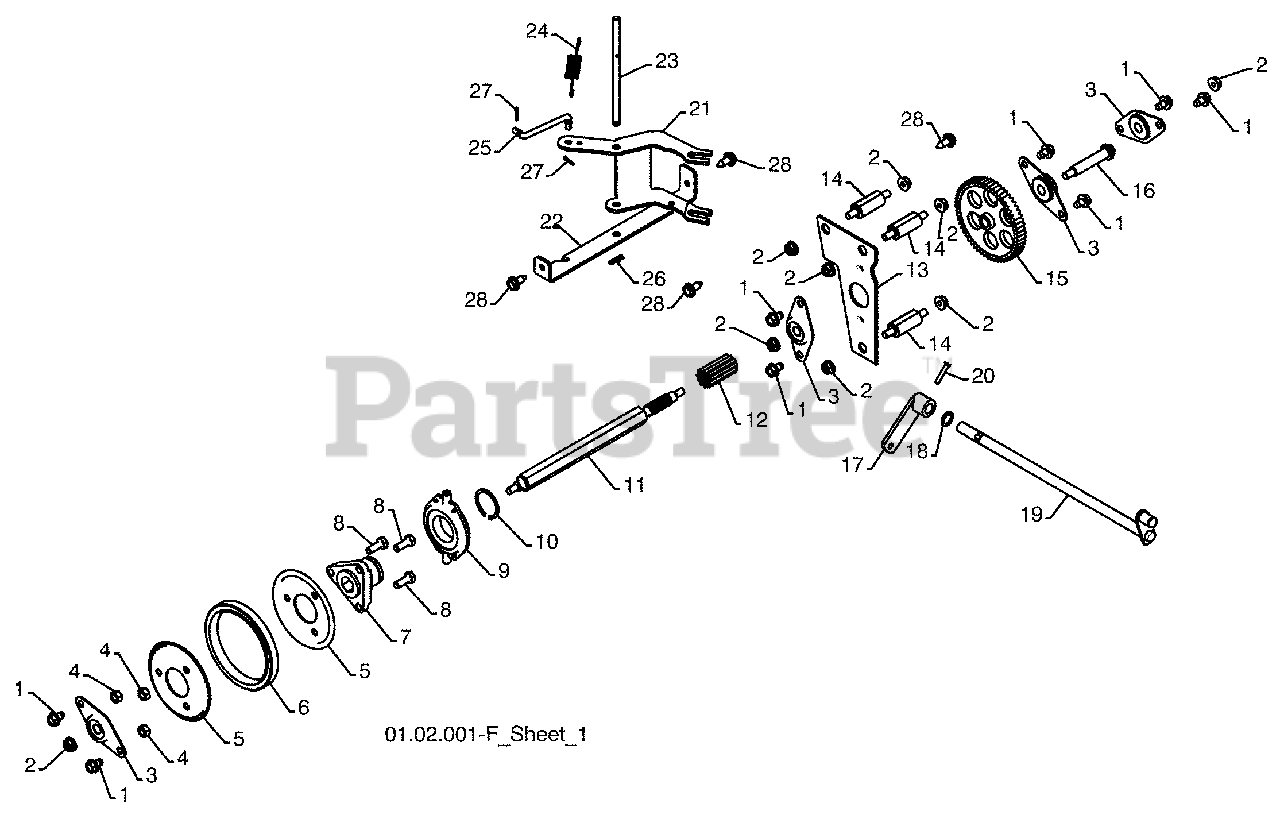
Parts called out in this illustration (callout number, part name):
1	BOLT 5/16-18 X .500
2	NUT 5/16-18
3	FLANGE BEARING
4	NUT 5/16-18
5	RUBBER WHEEL PLATE
6	RUBBER WHEEL RING
7	RUBBER WHEEL HUB
8	BOLT 5/16-18 X .875
9	TRUNNION BEARING ASSEMBLY
10	RETAINER
11	HEX SHAFT
12	PINION GEAR
13	AUXILIARY PLATE
14	SPACER PLATE
15	INTERMEDIATE GEAR
16	AUXILIARY SHAFT
17	CONTROL ARM
18	WASHER
19	CONTROL SHAFT ASSEMBLY
20	CLEVIS PIN
21	SHIFTER LEVER
22	PIVOT BRACKET
23	PIVOT PIN
24	SPRING
25	SHIFTER LINK
26	RETAINER
27	CLIP
28	BOLT 5/16-18 x .750
